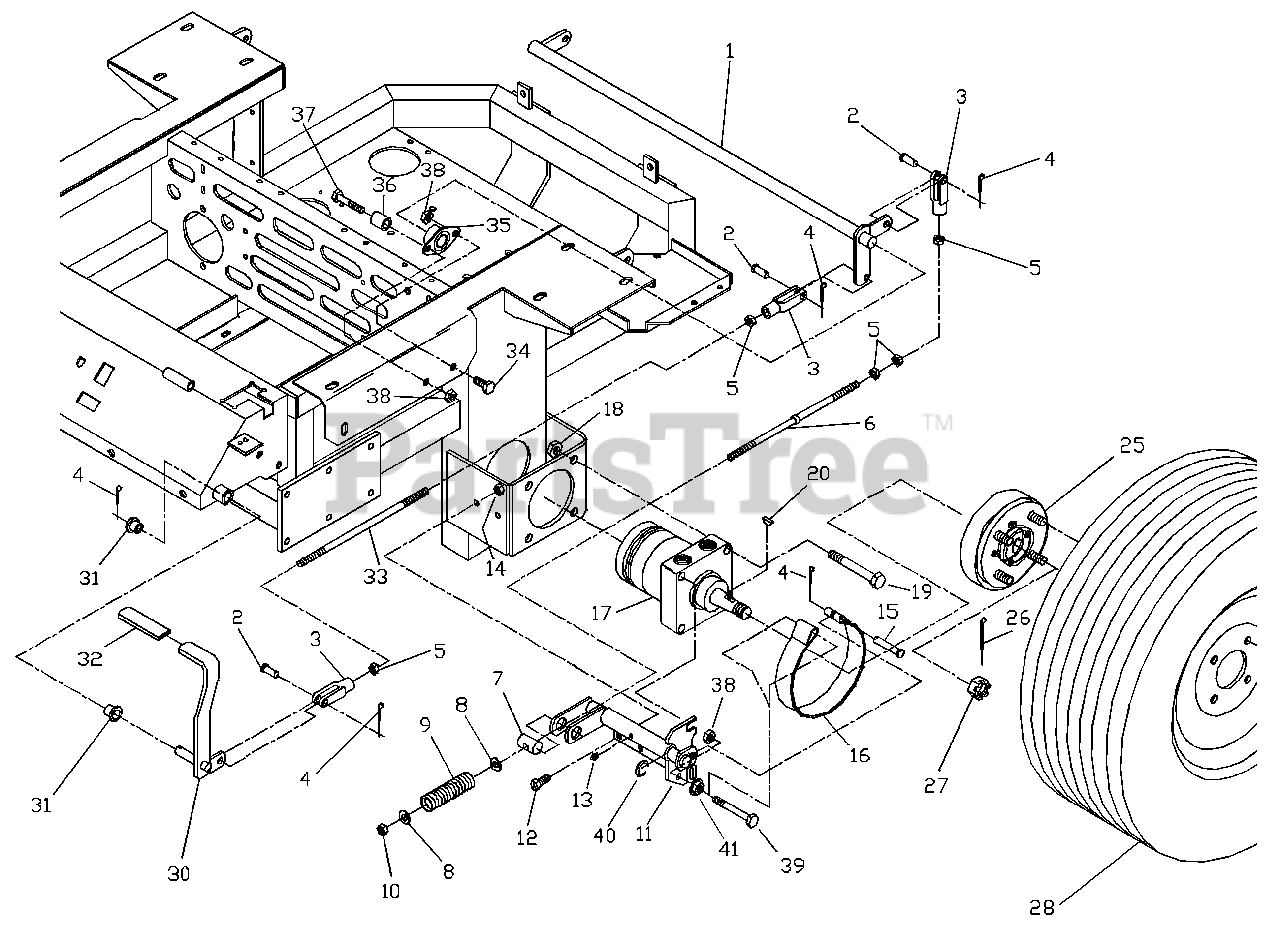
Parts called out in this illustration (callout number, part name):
1	BRAKE SHAFT
2	3/8 X 1 1/8 CLEVIS PIN
4	1/8 X 3/4 COTTER PIN
5	3/8F HEX NUT
7	TRUNION PIN
8	3/8 FLAT WASHER
10	3/8F CENTERLOCK NUT
11	BRAKE BRACKET, LEFT
12	5/16C X 1 HEX CAP SCREW
13	1/4 - 28 ZERK
14	5/16C CENTERLOCK NUT
15	3/8 X 1-1/2 CLEVIS PIN
16	BRAKE BAND
17	WHEEL MOTOR
18	1/2C NYLOC NUT
19	1/2C X 2 3/4 HEX CAP SCREW
20	KEY, #808 WOODRUFF
25	HUB WITH BRAKE DRUM
26	COTTER PIN
27	HEX SLOTTED NUT
28	WHEEL ASSEMBLY
28	VALVE STEM
28	TIRE
29	1/2F LUG NUT
30	BRAKE LEVER
33	BRAKE ROD, LONG
34	3/8C X 3/4 HEX CAP SCREW
35	FLANGE BEARING
36	BRAKE STOP
37	3/8C X 2 HEX CAP SCREW
38	3/8C CENTERLOCK NUT
39	3/8C X 2-1/2 HEX CAP SCREW
40	E RING 3/4
41	3/8C WHIZ NUT
